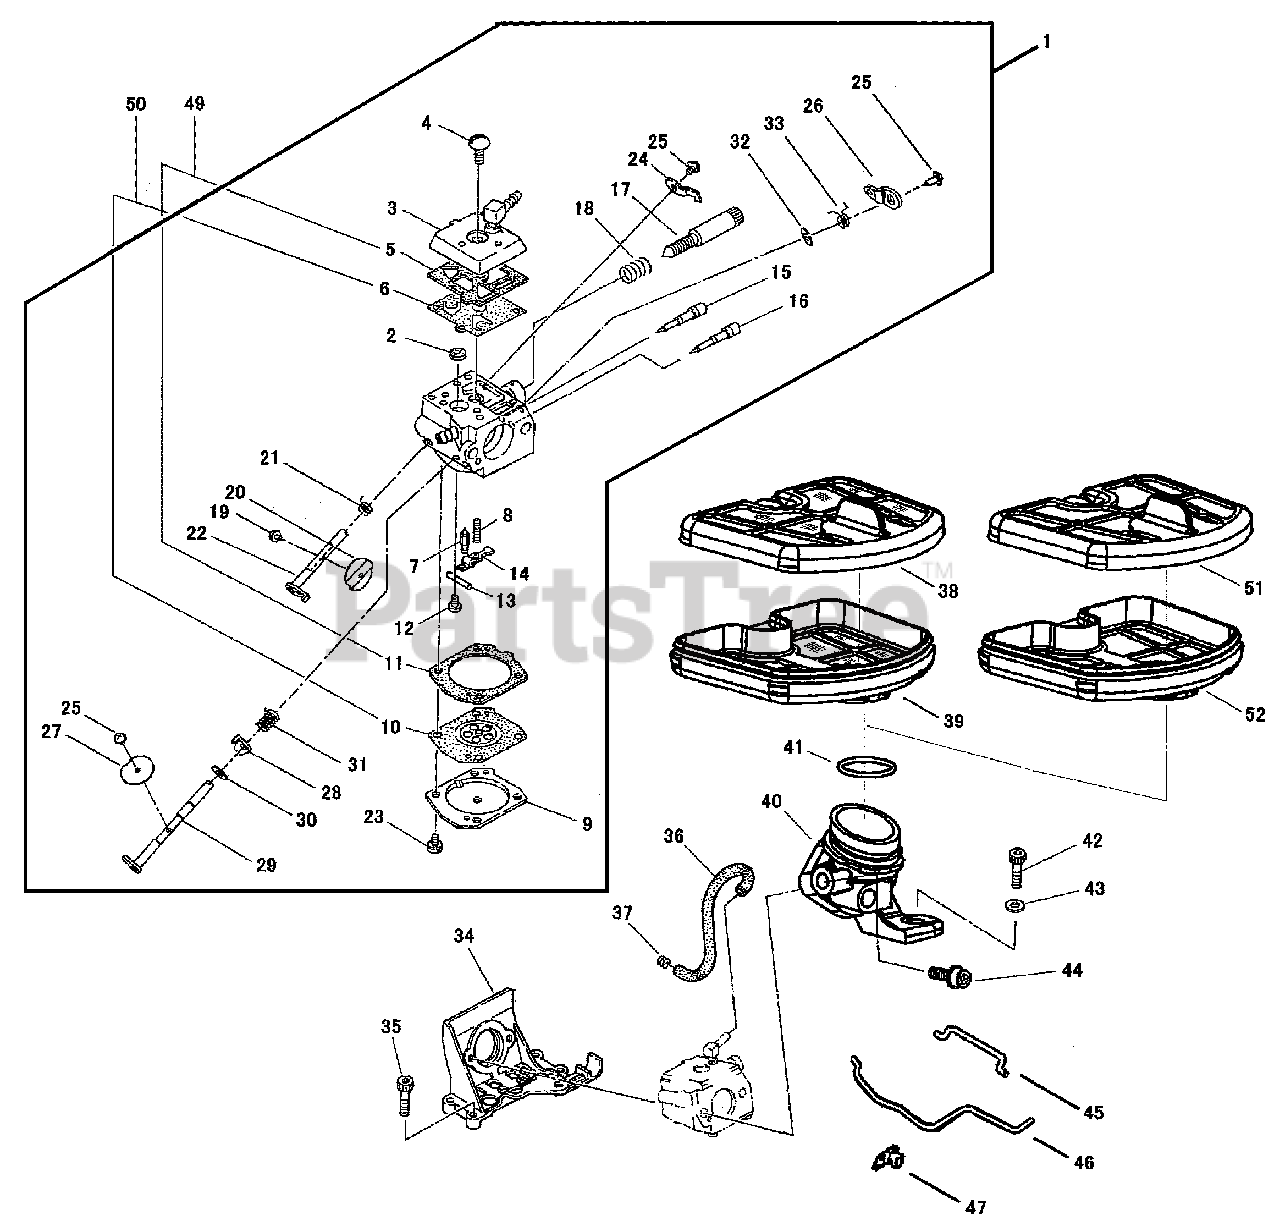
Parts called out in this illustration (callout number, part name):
1	CARBURETOR
2	SCREEN, FUEL INLET
3	COVER, PUMP
4	SCREW
5	GASKET, FUEL PUMP
6	DIAPHRAGM, FUEL PUMP
7	VALVE, INLET NEEDLE
8	SPRING, METERING LEVER
9	COVER, METERING DIAPHRAGM
10	DIAPHRAGM, METERING
11	GASKET, METERING DIAPHRAGM
12	SCREW, METERING LEVER PIN
13	PIN, METERING LEVER
14	LEVER
15	VALVE, NEEDLE
16	VALVE, NEEDLE
17	SCREW, IDLE ADJUST
18	SPRING, IDLE ADJUST
19	SCREW, THROTTLE VALVE
20	VALVE, THROTTLE
21	SPRING, THROTTLE RETURN
23	SCREW
24	STOP, THROTTLE
25	SCREW, THROTTLE STOP
27	VALVE, CHOKE
29	SHAFT
30	WASHER
31	SPRING, COIL
32	E-RING
34	MOUNT
35	BOLT M4×16
36	PIPE, PULSE
37	CLIP
38	AIR FILTER, NYLON UPPER
39	AIR FILTER, NYLON LOWER
42	BOLT M5×18
43	WASHER 5 MM
44	BOLT M5×50
45	ROD, CHOKE
46	ROD, THROTTLE
47	GROMMET
49	GASKET KIT
50	DIAPHRAGM KIT
51	AIR FILTER, UPPER FLOCKED
52	FILTER, LOWER FLOCKED AIR
